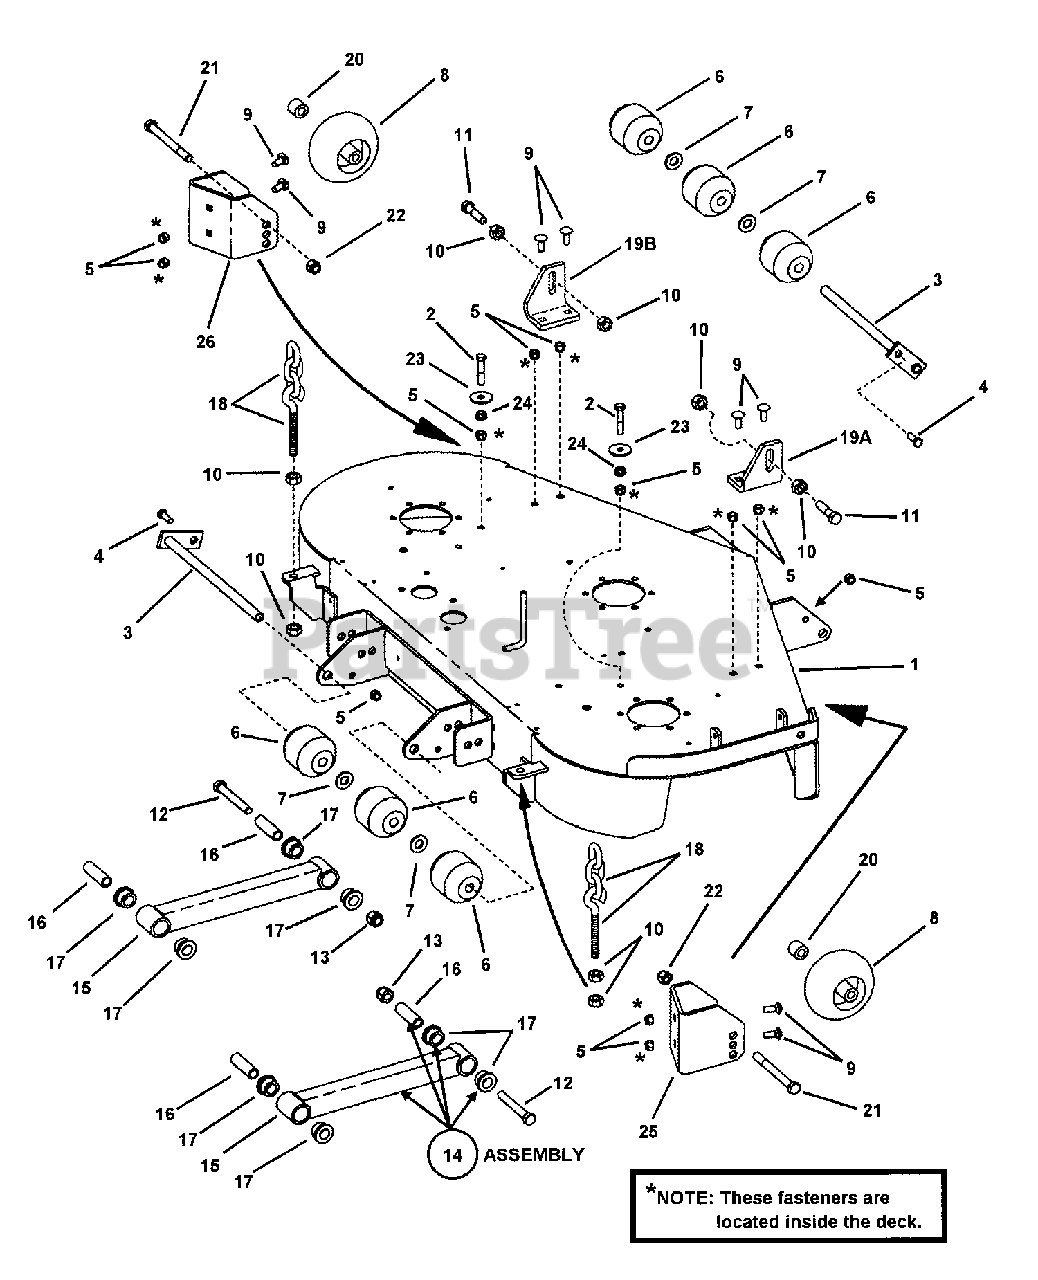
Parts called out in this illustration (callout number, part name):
1	WELDMENT, 52" Deck
2	BOLT, 3/8-16 X 2, GD5, CZ
3	WELDMENT Pivot Pin
4	BOLT, 3/8-16 X 1" GD5 CZ
5	NUT, 3/8-16 HEX NYLON LOCK
6	ROLLER Low Density Polyethylene
7	WASHER, 5/8" Flat SAE
8	GAUGE WHEEL, Polyethylene
9	BOLT, 3/8-16 x 1" Square Neck Carriage GR 5
10	NUT, 1/2-13 HEX
11	SCREW, 1/2-13 x 2" Hex Head Cap, GR 5
12	BOLT, 1/2-13 x 3-3/4" Hex Head Cap, GR 5
13	NUT, 1/2-13 HEX NYLON LOCK
15	WELDMENT, Pusher Bar
16	SLEEVE - Suspension
17	BUSHING - Suspension
18	ASSEMBLY, Chain & Eyebolt
19A	BRACKET, Front Deck Hanger R. H.
19B	BRACKET, Front Deck Hanger L. H.
20	SPACER, Gauge Wheel
21	BOLT, 1/2-13 X 5 GD5 YZ
22	NUT, 1/2-13 HEX NYLON LOCK
23	WASHER, .406 x 1.50 x .120 Flat
24	NUT, 3/8-16 HEX SERRATED FLANGE
25	WHEEL BRACKET Front Right
26	WHEEL BRACKET Front Left
